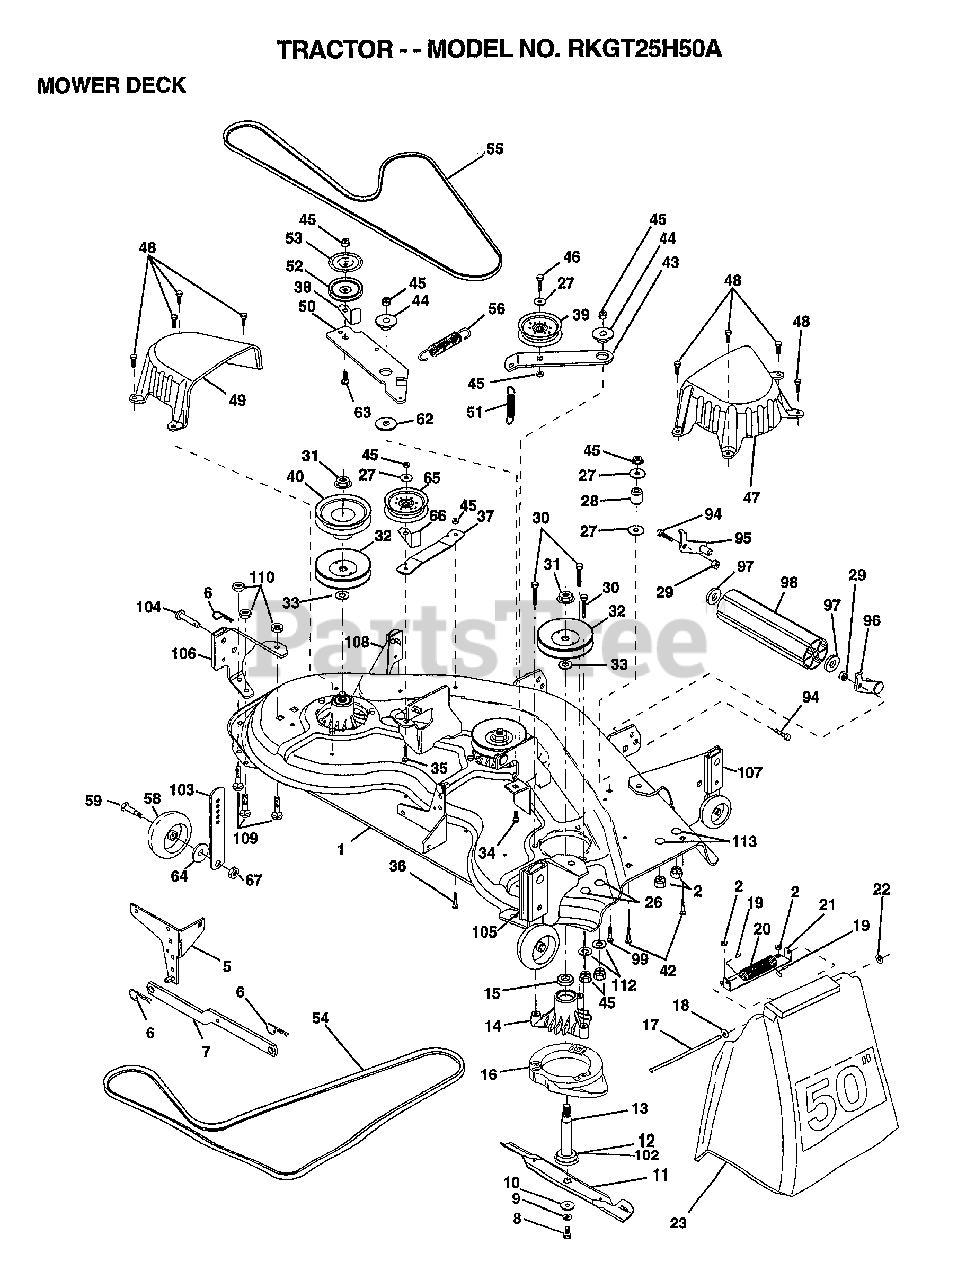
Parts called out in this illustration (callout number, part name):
1	"DECK ASM-50"""
5	BRKT.ASM.SW.44/50
8	BLADE BOLT
10	WASHER.HARD.BLADE
11	"BLADE.50"" HD"
12	BEARING.BALL
13	SHAFT.ASM.W/BRNG
14	HOUSING.MAND.44.V
15	BEARING
16	STRIPPER RND MWR
17	ROD-HINGE T
18	WASHER
19	CAP-SLEEVE LT
20	SPRING TORSION
21	BRKT DEFLECTOR
22	NUT PUSH M
23	DEFLECTOR
25	WASHER M
26	BOLT
27	WASHER
29	NUT
30	"SCREW-THD ROLL,WA"
32	PULLEY.MANDREL.42
33	WASHER
34	BOLT.3/8-14X1.25
35	BOLT
36	BOLT D
37	STIFFENER.ARM.IDL
38	"KEEPER-BELT,IDLER"
39	FLAT IDLER PULLEY
40	"PULLEY.DRIVEN.44"""
42	BOLT
43	"ARM.IDLER.SEC.44"""
44	SPACER RETAINER
47	"COVER.MAND.RH.44"""
48	SCREW.1/4-20X5/8
49	COVER.MANDREL.LH
50	ARM.IDLER.PRIMARY
51	"SPRING.SEC.44""VEN"
52	PULLEY.IDLER.VGRO
53	SHIELD.IDLER.44.V
54	BELT V PRIM 50
55	BELT-V.SEC.46.KEL
56	SPRING.EXT.DECK.
58	WHEEL GAGE DONUT
59	BOLT.SHOULDER
62	HARDENED WASHER
63	BOLT.3/8-16X1.50
64	WASHER
65	PULLEY IDELR FLAT
66	"KEEPER-BELT,IDLER"
67	LOCKNUT
94	BOLT
97	WASHER
99	BOLT
102	WASHER.FELT.
103	BAR.PNT.ADJUST.WHL.
104	RIVET-PAN HEAD
105	"BRKT ASM GA,WH,RR"
106	"BRKT ASM GA,WH,RR"
107	"BRKT ASM,GA,WH,FR"
108	"BRKT ASM,GA,WH,FR"
109	BOLT.CARRIAGE
112	WASHER
